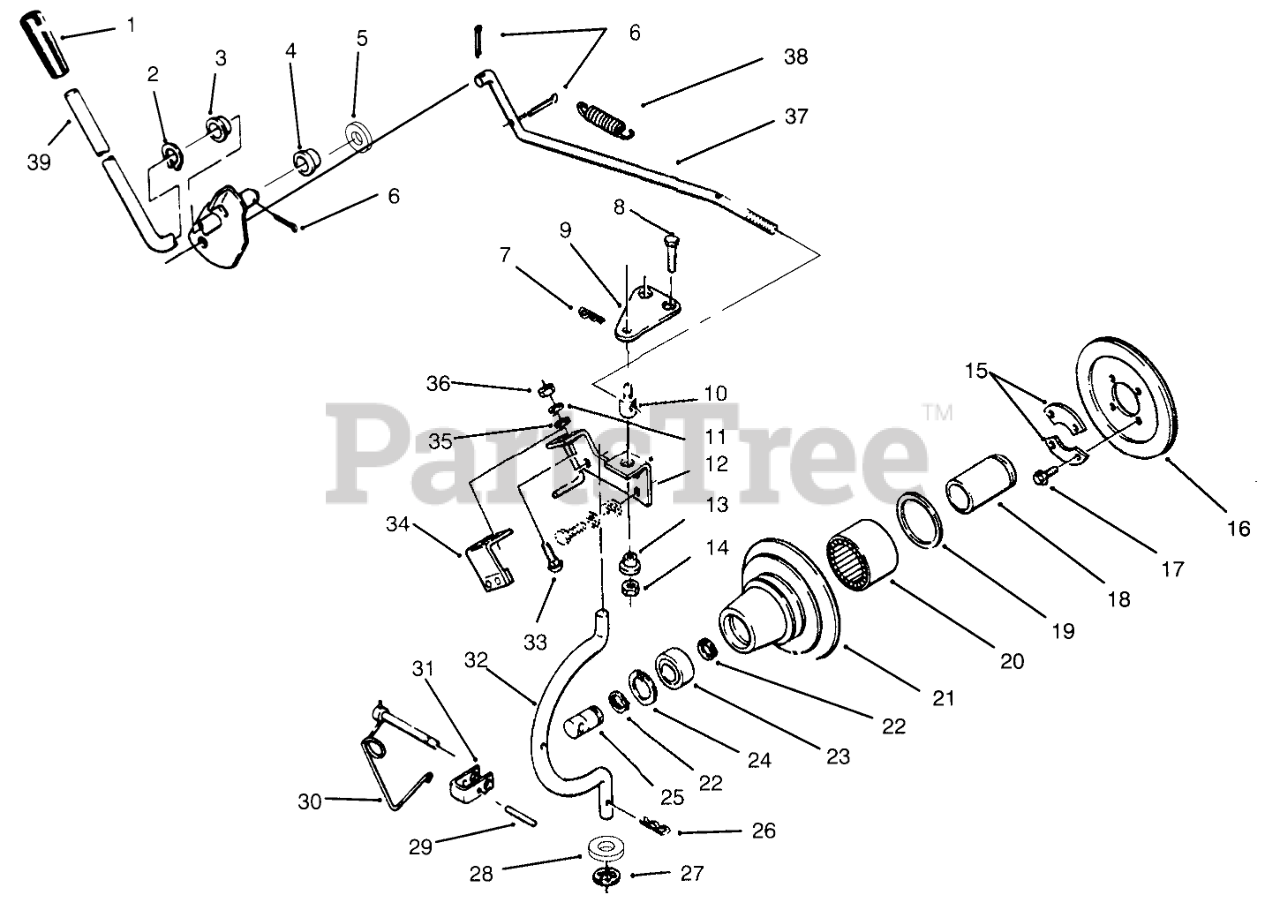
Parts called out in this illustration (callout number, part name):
1	GRIP
2	RING-EXT GRIP
3	BUSHING-NYLINER
4	NYLINER BUSHING
5	SHIM-WASHER
6	PIN-COTTER
7	Hairpin Cotter
8	SCREW-HH
9	PLATE
10	TRUNNION
11	WASHER-LOCK
12	Bracket-Engine
13	SPACER-LIFT LINK
14	NUT-LOCK, NI
15	RETAINER
16	Facing-Clutch
17	H H C S
18	RACE-BEARING
19	SEAL-OIL
20	Seal
21	Housing-Clutch
22	Ring-Snap
23	BEARING-BALL
24	RING-RETAINING
25	SHAFT-PTO
26	Hairpin
27	RING-REINFORCED CIRC
28	WASHER-FLAT
30	LOCKING PIN ASM
31	CLEVIS
32	ROD-HOUSING
33	SCREW-CARR
34	ASM-Bracket
35	WASHER-FLAT
36	NUT-JAM
37	ROD-PTO CLUTCH
38	SPRING
39	Lever-Clutch,PTO
